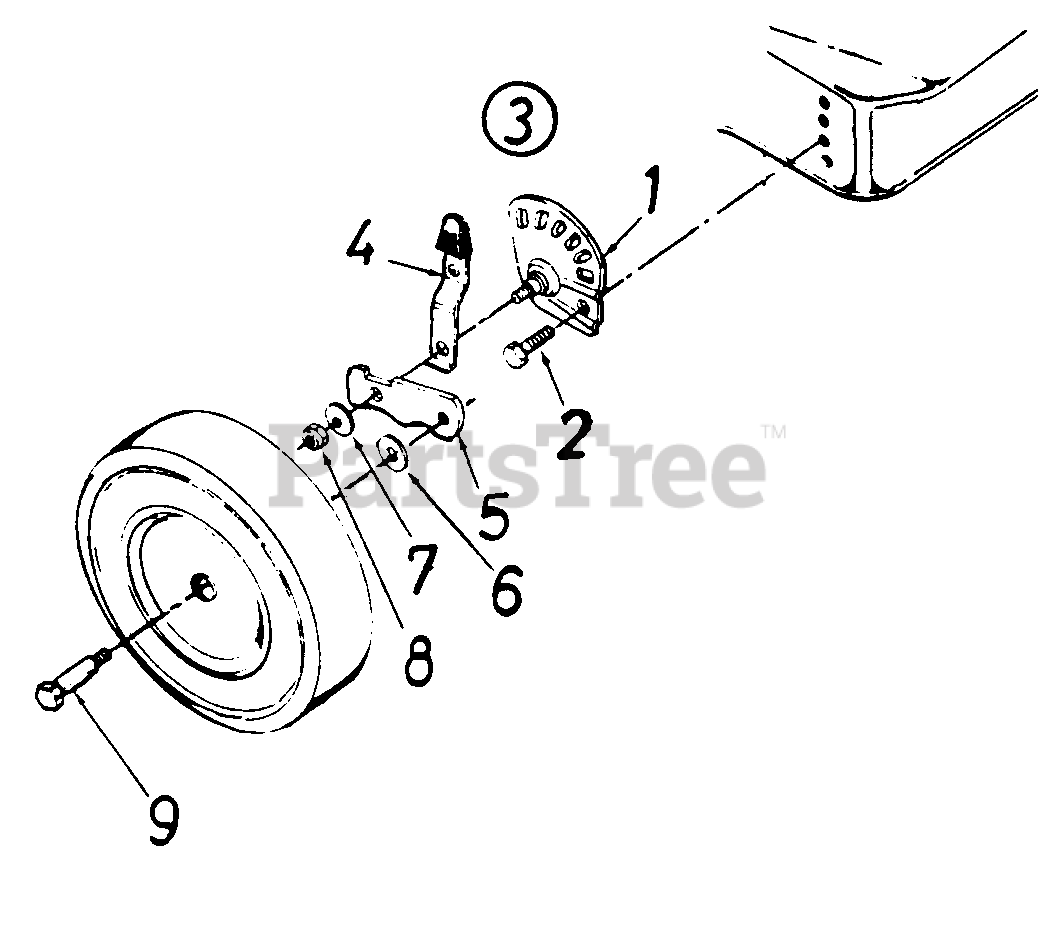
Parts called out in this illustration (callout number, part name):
1	Index Plate Ass'y. - R.H.
2	Hex Serns Bon 3/8-16 x .62" Lg.
3	Height AdJ. Ass'y. Comp. - R.H.
4	Spring Lever Ass'y. w/Knob
5	Pivot Bar
6	Bell-Wash. .4" I.D. x .88
7	Bell-Wash. .4" I.D. x 1.13
8	Elastic L-Nut 3/8-24 Thd.
9	Axle Bolt
